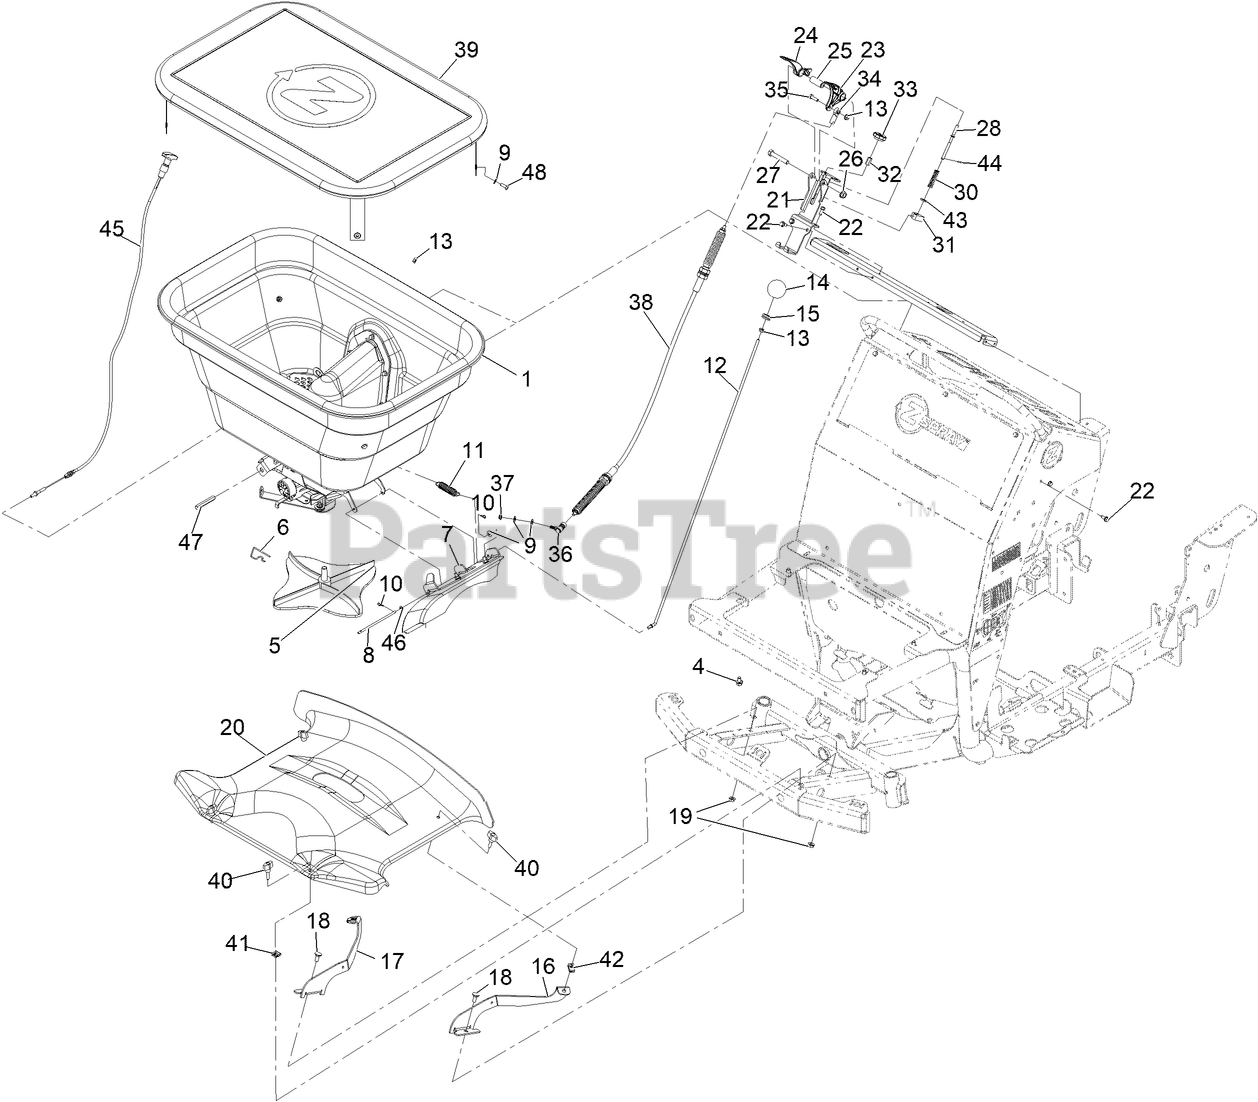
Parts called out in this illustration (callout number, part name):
1	Spreader Hopper ASM
4	SCREW-HHF
5	Spinner-Spreader
6	Clip-Spinner
7	Side Deflector ASM
8	PIN-DEFLECTOR SS
9	WASHER-FLAT
10	PIN-COTTER, HAIR
11	SPRING-EXTENSION
12	ROD-CONTROL, DEFLECTOR
14	KNOB-RATE, FLOW
15	GROMMET
16	BRACKET-COVER, FRONT (LH)
17	BRACKET-COVER, FRONT (RH)
18	SCREW-CARR
20	COVER-FRONT, SPREADER/SPR
21	MOUNT-HANDLE
22	SCREW-HWH
23	LEVER-SPREAD, WIDE
24	LEVER-SPREAD, NARROW
27	SCREW-HH
28	LINK-ADJUST, NARROW
30	SPRING-COMPRESSION, BAIL
31	STOP-SPREAD, NARROW
32	NUT-COUPLER
34	ROD END-BALL JOINT
35	SCREW-HH
36	BALL-JOINT
37	NUT-HEX, NI
39	Cover-Hopper, Clear Vinyl Window
41	NUT-RETAINER, U STYLE
42	NUT-RETAINER
43	WASHER-FLAT
44	PIN-COTTER
45	CABLE-CONTROL, TURN LOCK
46	WASHER-FLAT
47	POST-HEX, DIFFUSER GUIDE
48	SCREW-HH
